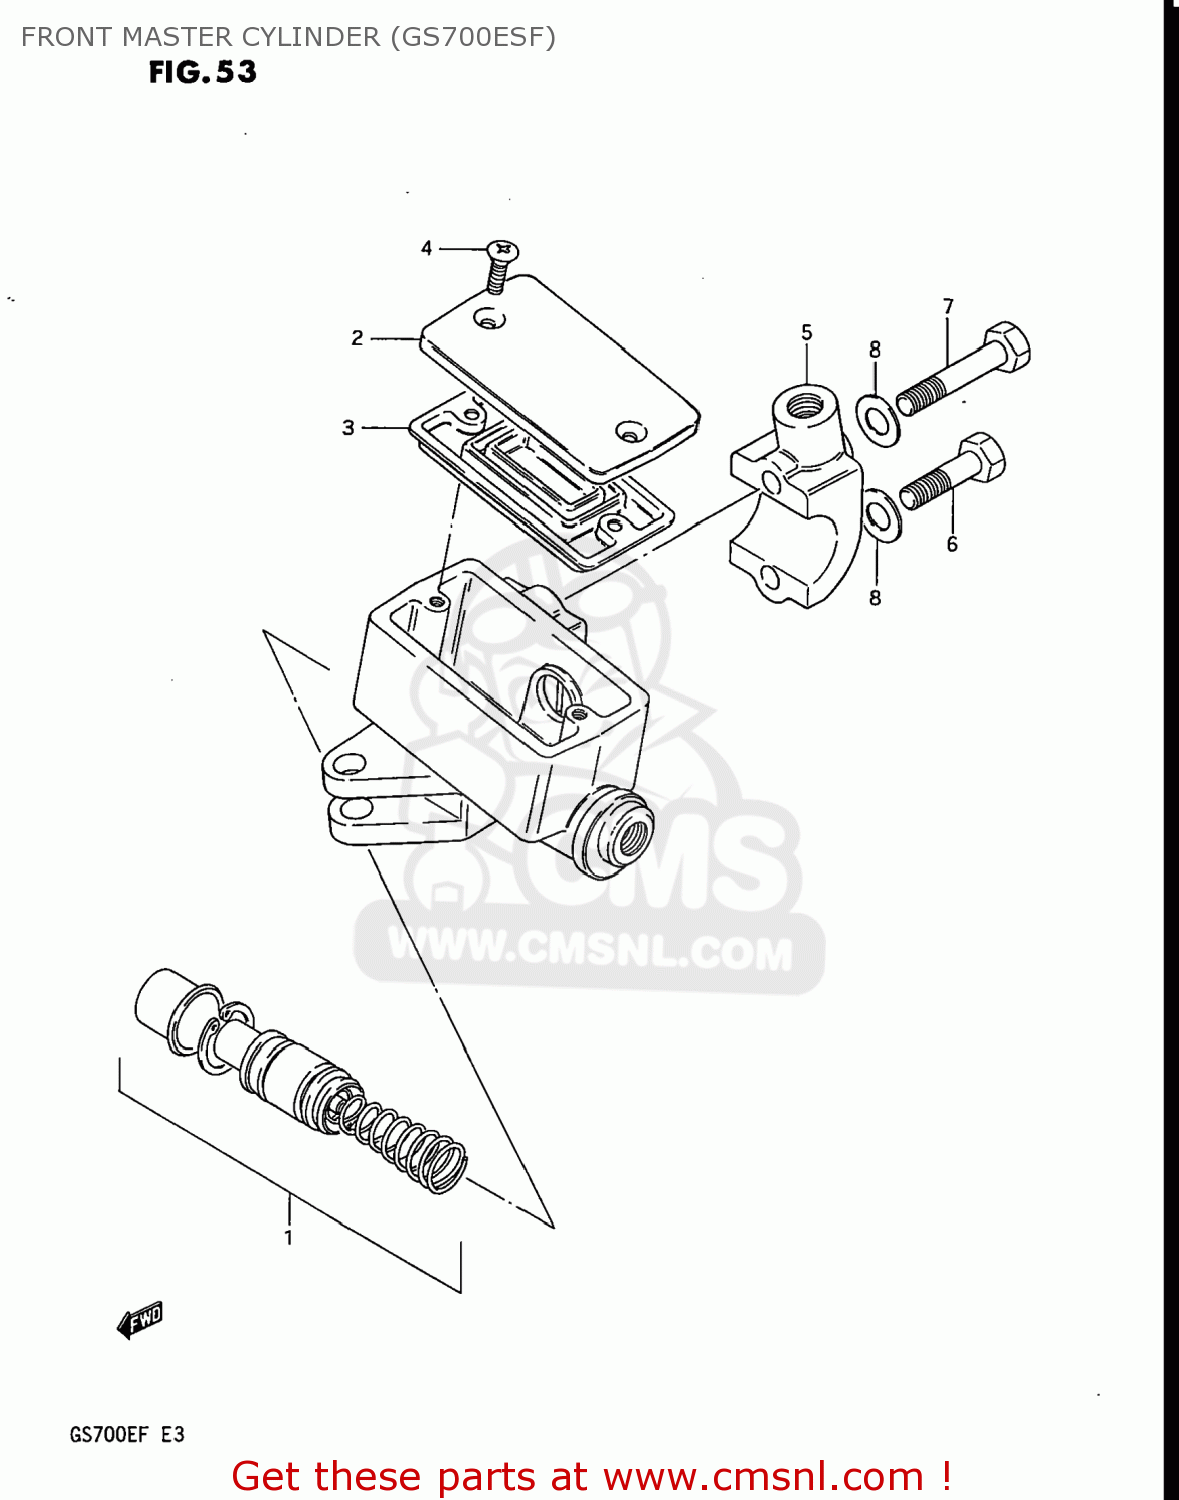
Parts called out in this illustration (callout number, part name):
1	PISTON & CUP SET
2	CAP
3	4
4	SCREW
5	HOLDER
6	BOLT
7	BOLT
8	WASHER
